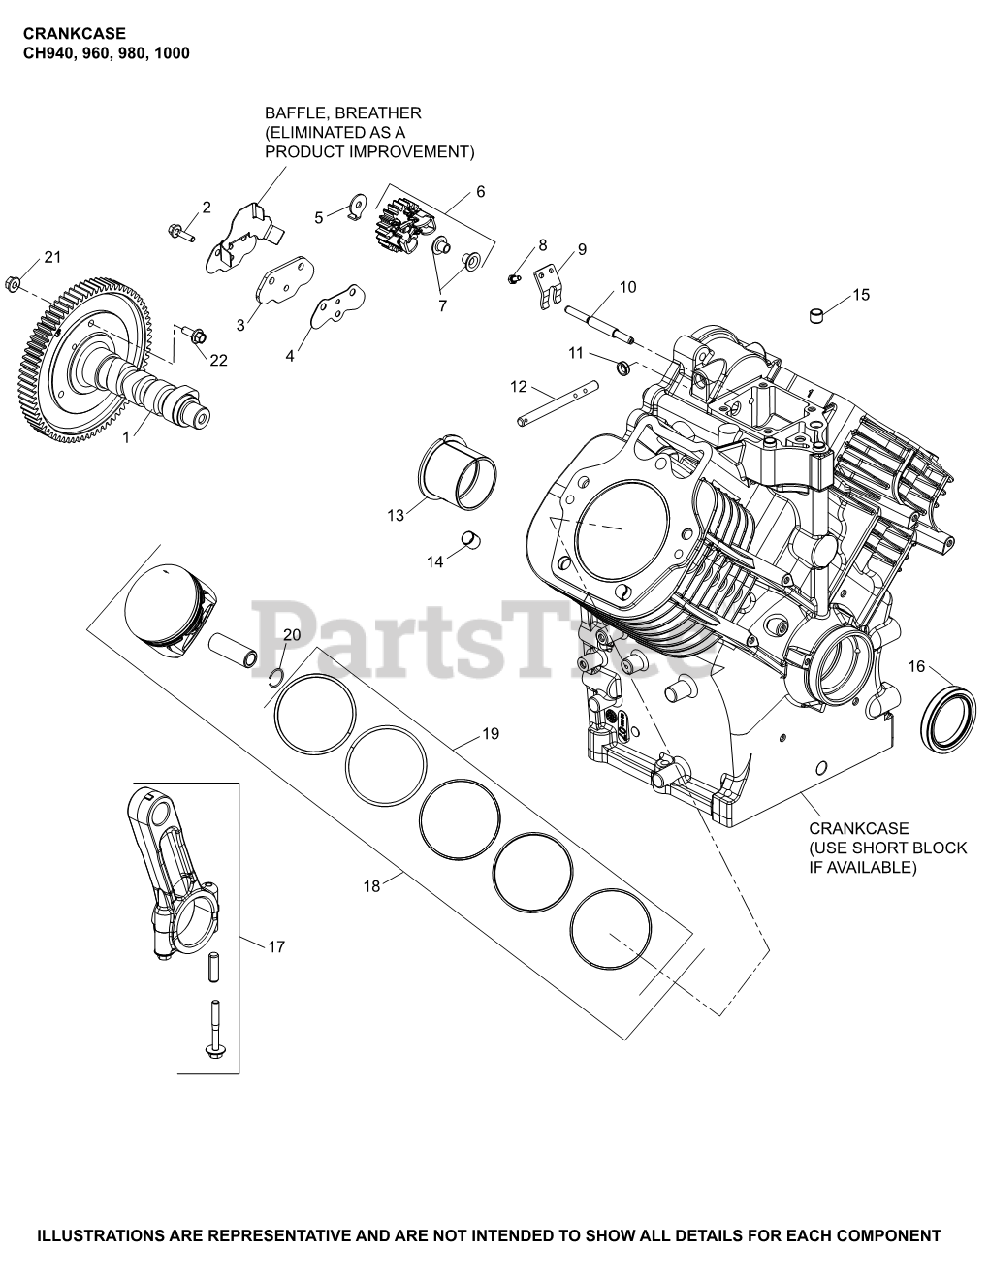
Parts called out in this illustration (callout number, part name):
1	KIT, CAMSHAFT USE 62 010 12-S
2	SCREW, HVY FLG M5X0.8X20
3	KIT, COVER, LIFTER FEED
4	GASKET, LIFTER FEED COVER
5	TAB, LOCKING
6	GOVERNOR GEAR ASSEMBLY USE 25 310 09-S
7	PIN, GOVERNOR REGULATING
8	SCREW, HEX HEAD
9	YOKE, GOVERNOR
10	SHAFT, GOVERNOR GEAR
11	SEAL, GOVERNOR CROSS SHAFT
12	SHAFT, GOVERNOR CROSS
14	PIN, LOCATING
16	SEAL, OIL
17	CONNECTING ROD ASSEMBLY
18	KIT, PISTON (STD) (See Kohler Note)
18	KIT, PISTON (0.25 OS)
18	KIT, PISTON (0.50 OS)
19	RING, SET PISTON (STD)
20	RETAINER, PISTON PIN
21	NUT, FLG M6X1.0
22	SCREW,HEX FLNGE
